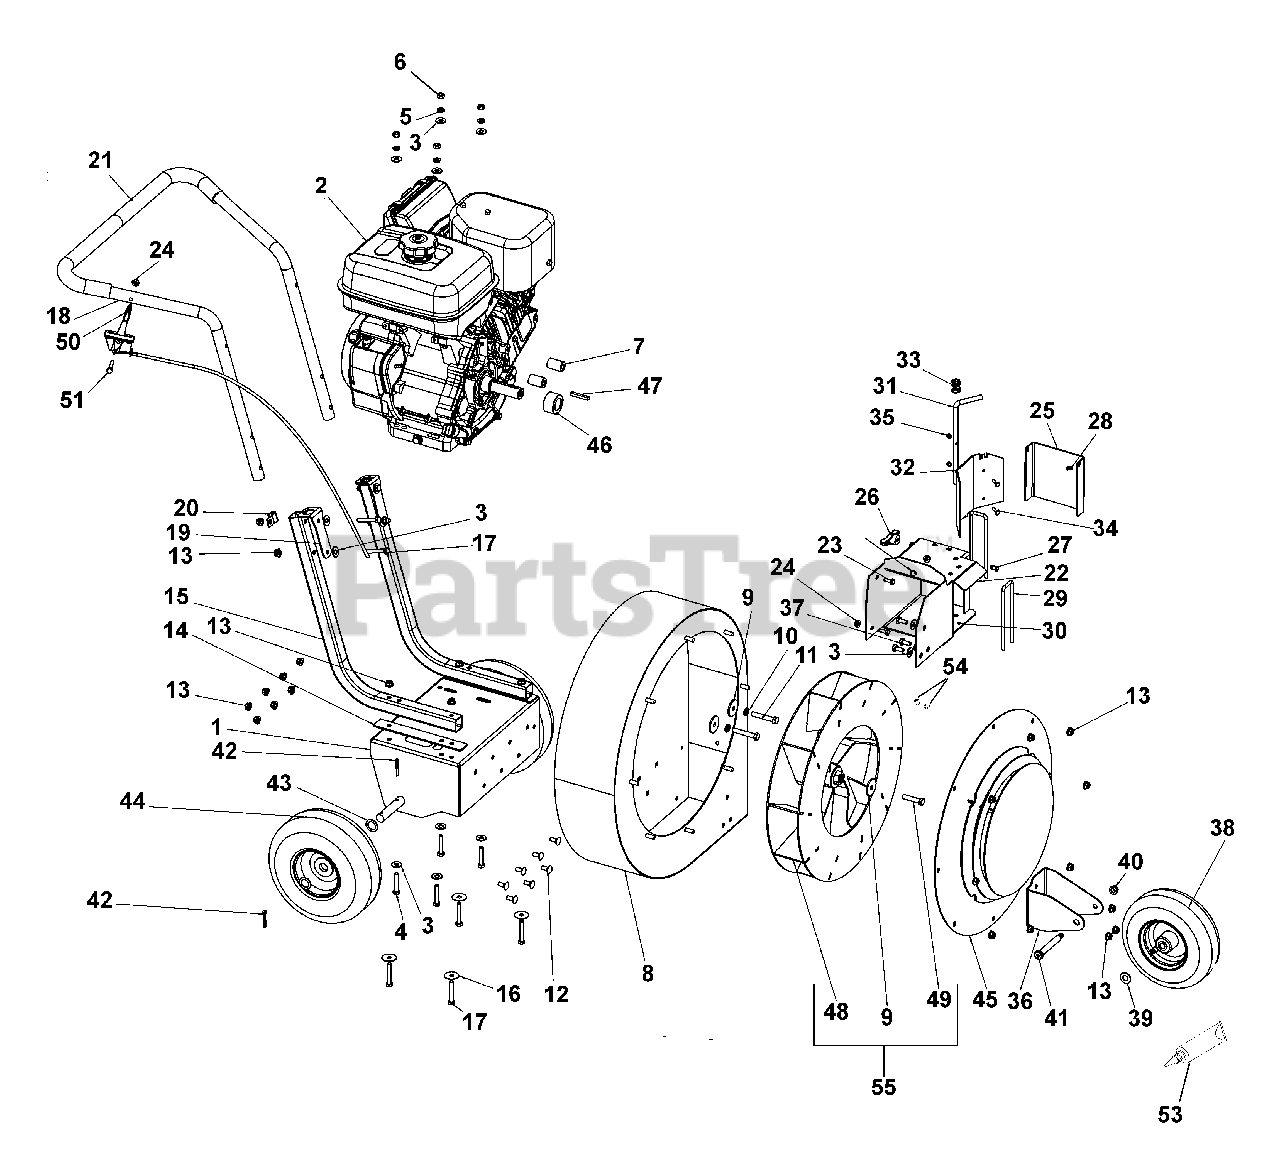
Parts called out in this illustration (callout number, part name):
1	WMT-FRAME, BLOWER LARGE
2	ENGINE, SUBARU EX40
3	@WSHR-FL-STL.38X.875X.083 YWZC
4	@BLT-HEX .31-18X1.75 GR5 YWZC
5	WSHR-LK .312X.097 HVY YWZC
6	@NUT-HEX .31-18 YWZC
7	SPACER, .38X.875X1.38
8	WMT-BLOWER HOUSING LG
9	WSHR-FL-STL,.390X1.00X.25 YWZC
10	@WSHR-LK .38X.094 REG YWZC
11	@BLT-HEX .38-16X2.25 GR5 YWZC
12	@BLT-RDHDSQNK .31-18X.75 G5YZ
13	@NUT-LK-NYL-FLG .31-18 YWZC
14	SPACER-RUBBER
15	TUBE-HANDLEBAR, LOWER SQ
16	WSHR-FL-STL .347X1.254X.048YWZ
17	@BLT-HEX .31-18X2.00 GR5 YWZC
18	TUBE-HANDLEBAR, UPPER
19	BRKT-HANDLEBAR MOUNT
20	J-CLAMP
21	GRIP-HANDLEBAR, UPPER
22	WMT-CHUTE, BLOWER LG
23	@BLT-HEX .25-20X.75 GR5 YWZC
24	@NUT-LK-NYL-FLG .25-20 YWZC
25	BRKT-CAP, CHUTE LG
26	KNOB,WING .31-18 UNC NYL/TALC
27	PIN-CLEV .313X.500 YWZC
28	PIN-HAIR, ENDRIES #25 YWZC
29	WIREFORM-GUARD, SAFETY LG
30	NUT-PUSH .25X.50 O.D.
31	WIREFORM-LEVER, DIRECTION
32	BRKT-DEFLECTOR, AIR BAFFLE
33	SPRING-COMP 1.0LX.72 OD .05DIA
34	@SCR-MCH 10-24X.75 HWH YWZC
35	@NUT-LK-NYL 10-24 W/INSRT YWZC
36	BRKT-WHEEL, FRONT
37	@BLT-HEX .31-18X.75 GR5 YWZC
38	WHEEL-9X2.5 PNEU- WHITE RIM
39	WSHR-FL-NYL .518X1.000X.080
40	@NUT-LK-TOP-FLG .38-16 YWZC
41	BLT-SHLDR .5X3.25X.38-16
42	@PIN-CTR .16X1.25 EXTPRSQCT YZ
43	WSHR-FL-STL.754X1.125X.062YWZC
44	WHEEL-10X3.75 PNEU. WHITE
45	WMT-INLET GUARD LG
46	BSHG-SLV, 1.0X1.75X1.0
47	KEY-STR .25X1.75X.25
48	WMT-FAN, LG W/SET SCR
49	BLT-HEX .38-24X1.75 G8 YZ EP80
50	THROTTLE CONTROL
51	@BLT-HEX .25-20X2.00 GR5 YWZC
52	WSHR-FL-STL .390X.88X.18 YWZC
53	ADHESIVE-LOCTITE 609 .5ML
54	SCR-SET .31-18X.38 SKHCUPDL
55	KIT-14HP FAN REPLACEMENT
